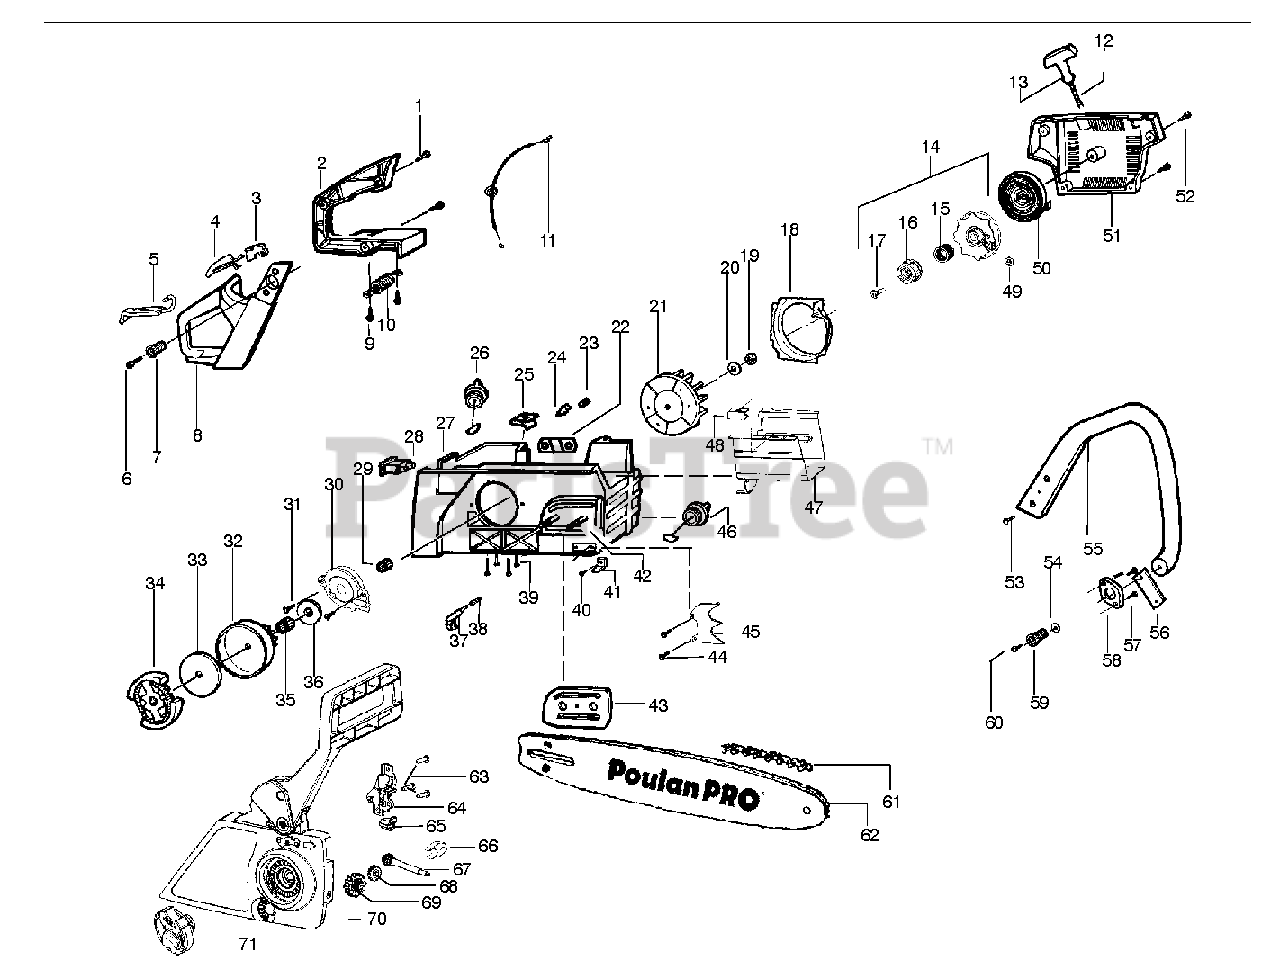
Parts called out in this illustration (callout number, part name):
2	HANDLE
3	THROTTLE TRIGGER
4	THROTTLE LOCK
5	CHOKE LEVER
8	HANDLE
9	SCREW,FRONT HBAR 36/41
11	THROTTLE WIRE
12	KIT-ROPE
13	STARTER HANDLE
14	KIT EPS STARTER
15	SPRING EPS
16	HUB STARTER EPS
17	SCREW SHOULDER
19	NUT-FLYWHEEL
20	WASHER-FLYWHEEL
21	FLYWHEEL ASSY
22	PLATE,BAR MOUNT
23	VENT,FUEL TANK 36/41
24	VALVE-CHECK (DUCKBILL)
26	FUEL CAP CPL
27	CHASSIS ASSEMBLY
29	OILER GEAR 36/41
30	OILER ASS'Y 36/41
32	SPUR SPRKT .325 7T 36/41
33	FRICTION DISC,CLUTCH 36/41
34	CLUTCH ASSEMBLY
35	NEEDLE BEARINGS 36/41
36	DUST COVER 36/41
37	PICKUP OIL P600-P
38	SCREEN/FILTER
39	SCREW M5-0.8X35M TAP
41	CHAIN CATCHER 36/41
42	BAR BOLT 36/41
43	BAR PLATE
45	SPIKE 36/41
46	OIL TANK CAP
47	SHIELD-HEAT
50	SPRING STARTER
51	FAN HSG P600 PRO GOLD
52	SCREW,STRTR CVR 36/41
54	WASHER
55	%HANDLE
57	SCREW 8-16 X 9/16 (PLAS
61	CHAIN 20" (78/325-050)
62	BAR 20" QUICK ADJUST
64	COVER GEAR
65	Adjusting Bar Pin
67	Bar Adjuster Screw
68	Idler Gear
69	%WHEEL GEAR ADJUSTMENT
70	CHAIN BRAKE ASSY
